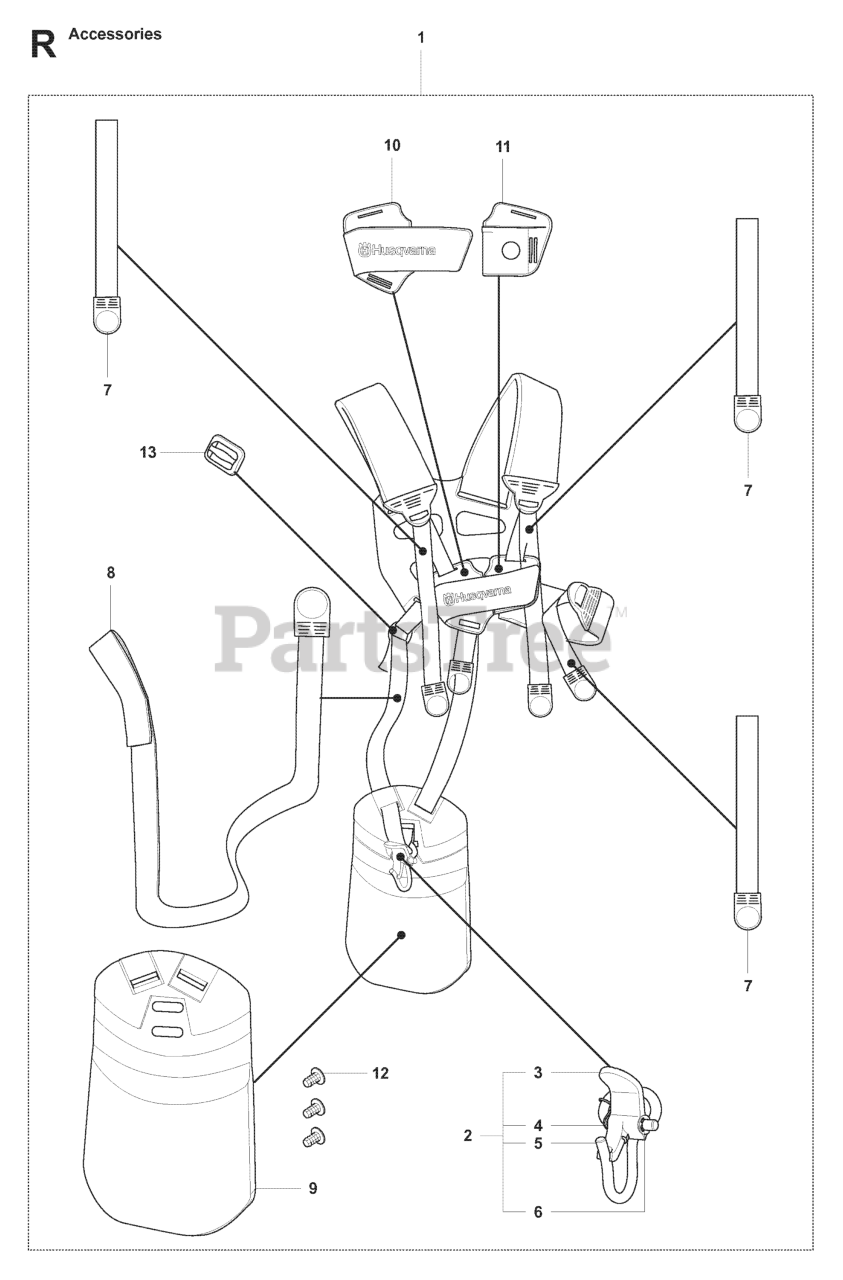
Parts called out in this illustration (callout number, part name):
1	Duo-Bal Harness
2	HARNESS HOOK, COMPLETE
3	CATCH *
4	SPRING
5	HOOK
10	FRONT PIECE
11	FRONT PIECE
13	RP CLIP
